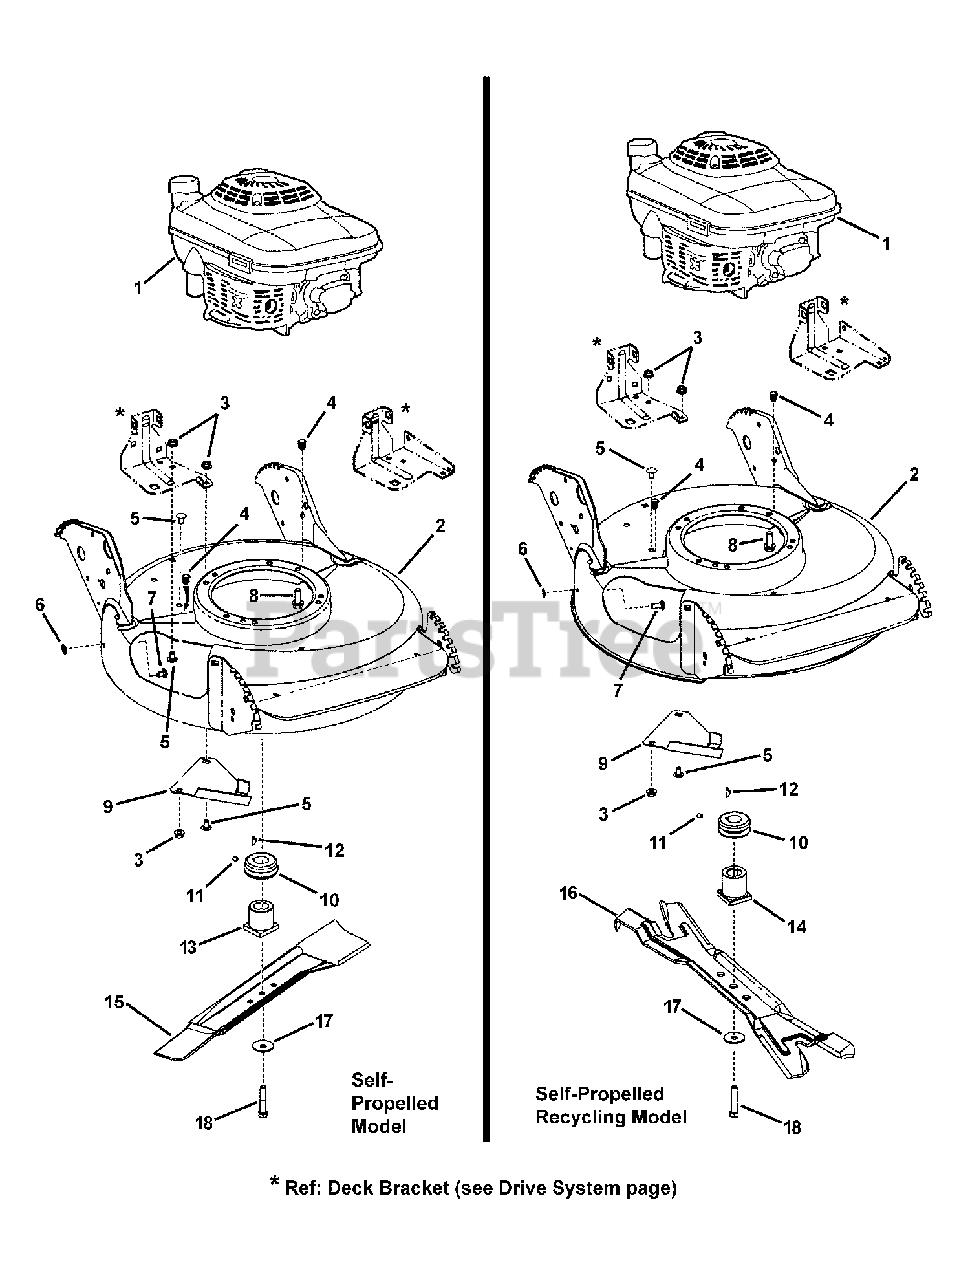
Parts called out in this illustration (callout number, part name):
1	* ENGINE, Kawasaki 6 HP w/side recoil
1	* ENGINE, Kawasaki 6 HP
2	WELDMENT, Deck, 21" Non-Adjust Air
2	WELDMENT, Deck, 21", S.P., HV, Core Model
3	NUT, 5/16-18 Hex Flange Lock, GR 5
4	PLUG, Hole, Polyethylene
5	BOLT, 5/16-18 x 1/2", Short Neck Carriage, GR 5
6	RETAINER, 5/16" Bolt
7	BOLT, 5/16-18 x 3/4" Short Neck Carriage GR 5
8	SCREW, 3/8-16 x 1" Self-Tapping
9	COVER, Belt
10	PULLEY, Engine (25mm I. D. x 2-1/8" O.D.)
11	SET SCREW, 5/16-18 x 5/16" Hex Socket
12	KEY, Woodruff #HP-506 Hi-Pro
13	HUB, Blade Drive, 25 mm I.D.
14	HUB, Blade, 21" WBM, RD, 2 Position
15	BLADE, 21" Standard Lift
16	BLADE, 21" Ninja (Quad Edge)
17	WASHER, Cone 3/8"
18	SCREW, 3/8-24 x 2" Hex Head Cap, GR 5
